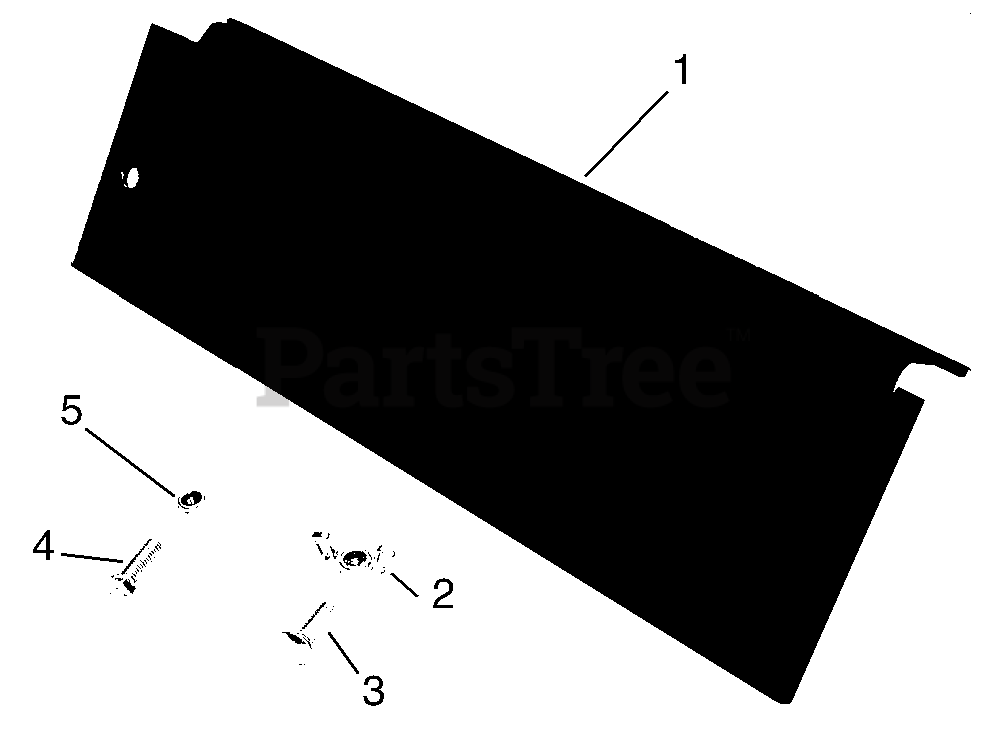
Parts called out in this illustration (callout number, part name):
1	COVER, UNIVERSAL DISCHARGE
2	NUT-NYLK WING .312-18 YWZC
3	@BLT-RDHDSQNK .31-18X1.00 G5YZ
4	@BLT-HEX .31-18X1.00 GR5 YWZC
5	@NUT-LK-NYL .312-18 YWZC
